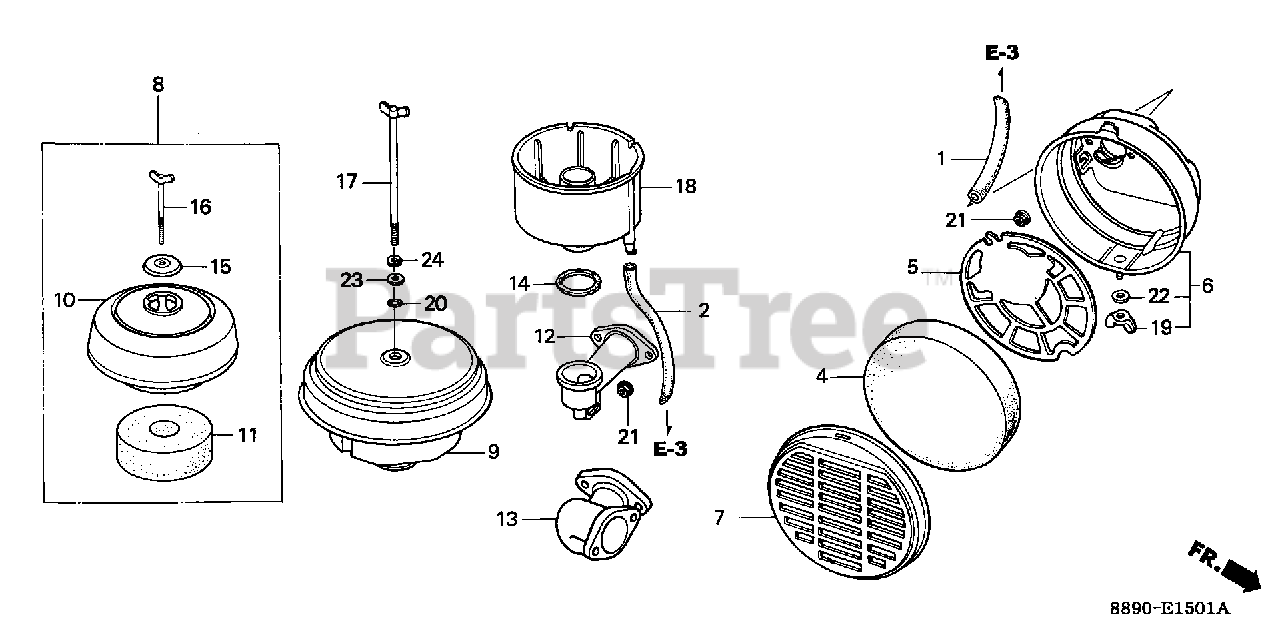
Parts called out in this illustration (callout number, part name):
1	TUBE, BREATHER
2	TUBE, BREATHER (NOT AVAILABLE)
4	ELEMENT, AIR CLEANER
5	GRID, AIR CLEANER
6	HOUSING, AIR CLEANER
7	COVER, AIR CLEANER
8	BODY KIT, AIR CLEANER (NOT AVAILABLE)
9	HOUSING, AIR CLEANER *NH31R* (MCKINLEY WHITE)
10	BODY, AIR CLEANER (NOT AVAILABLE)
11	ELEMENT, AIR CLEANER
12	ELBOW, AIR CLEANER
14	GASKET, IN. ELBOW (NOT AVAILABLE)
15	CAP, AIR CLEANER (NOT AVAILABLE)
16	BOLT, AIR CLEANER
17	BOLT, AIR CLEANER
18	PAN, CLEANER OIL (NOT AVAILABLE)
19	NUT, TOOL BOX SETTING
20	O-RING (5X2.4)
20	O-RING (4.9X2.5)
21	NUT, FLANGE (6MM)
22	WASHER, PLAIN (6MM)
23	WASHER, PLAIN (6MM)
24	WASHER, SPRING (6MM)
